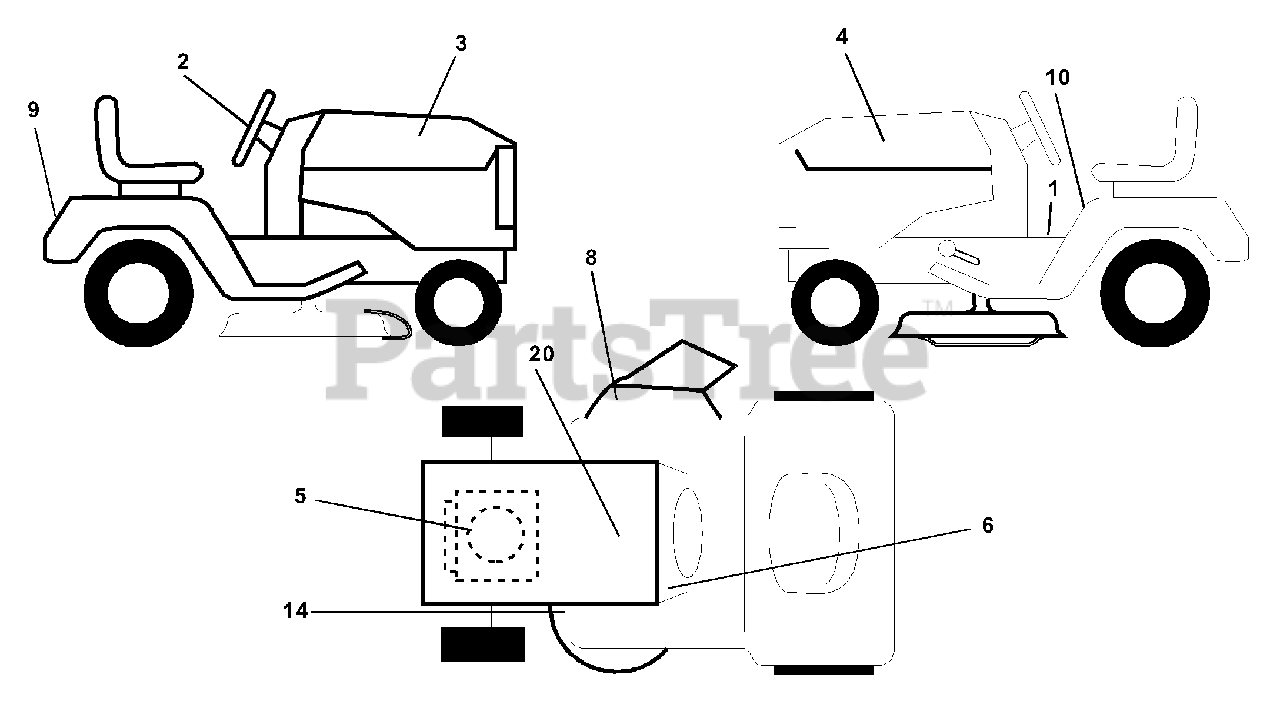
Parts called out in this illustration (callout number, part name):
1	Decal Oper Step Thru E/F
2	Decal Strg Wheel Logo
3	Decal Hood RH
4	Decal Hood LH
5	Decal Engine
6	Decal Dash Logo
8	Decal Warning
9	Decal Fender Husq
10	Decal Fender Danger E/F
14	Decal V-Belt Schematic
20	Decal Bat Dan/Psn
